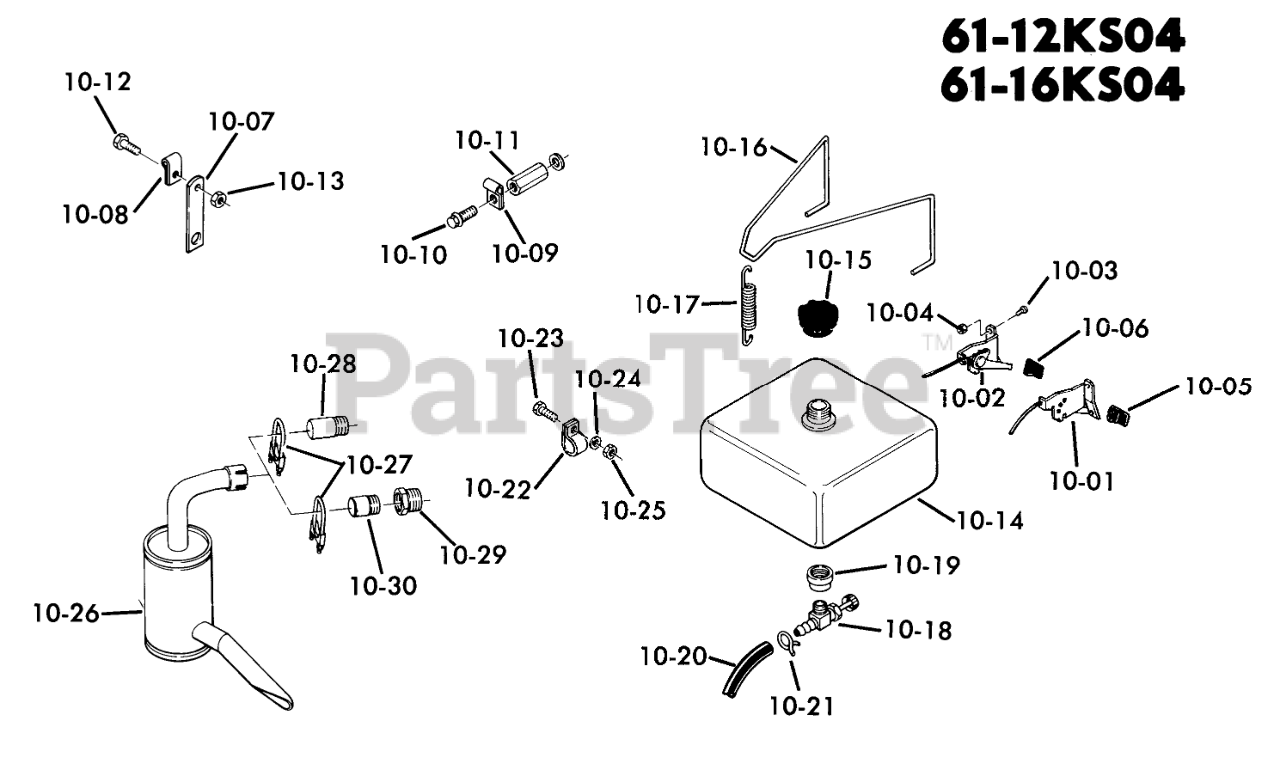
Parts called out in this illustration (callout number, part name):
10-01	Choke Control
10-02	THROTTLE CONTROL
10-03	SCREW
10-04	#10-24 Kep-Nut
10-05	KNOB-CHOKE
10-06	KNOB-THROTTLE
10-07	Strap
10-08	THROTTLE CONTROL CLP
10-09	Clip
10-10	Screw
10-11	Special Nut
10-12	Screw
10-13	Nut
10-14	ASSY-FUEL TANK
10-15	Cap
10-16	HOLD DOWN WIRE
10-17	CLUTCH SPRING
10-18	VALVE-FUEL
10-19	BUSHING
10-20	Fuel Hose
10-21	Clamp
10-22	CLAMP-HOSE
10-23	Bolt
10-24	WASHER 5/16 SAE
10-25	Nut
10-26	Muffler
10-27	ASSY-MUFFLER CLAMP
10-28	NIPPLE
10-29	REDUCER 1 1/4-1
10-30	NIPPLE- 1X2 SPECIAL
